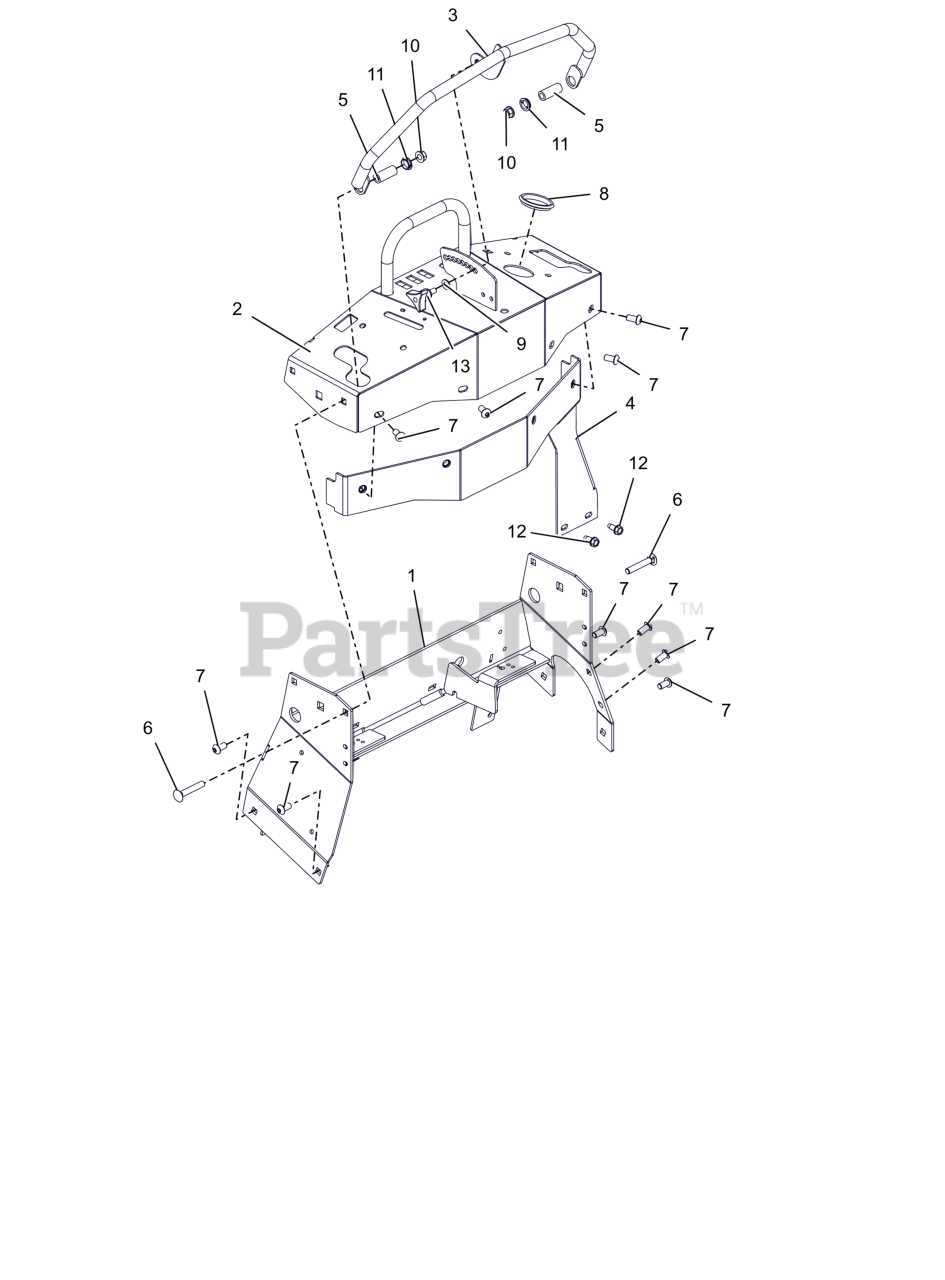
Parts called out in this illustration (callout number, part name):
1	WLDMT, TOWER (RED)
2	WLDMT, DASH (RED)
3	WLDMT, CRUISE BAR
4	WLDMT, DASH ACCENT (BLACK)
5	SPACER, .375 X .625 X 1.54
6	BLT,RHSN .38-16X2.25 G5 ZCC
7	SCR,BTNHD .375-16X.75 ZCC
8	GROMMET, RUBBER 1.89 ID
9	WSHR,FLT .344X.688X.065 ZCC
10	NUT-LK-CTR-FLG .375-16 GF ZCC
11	BUSHING, POLYLINER-.63 SNAPIN
12	SCR,TAP .312-18X.75 HWH TR ZCC
13	KNOB,WING STUD 5/16-18 X .75
